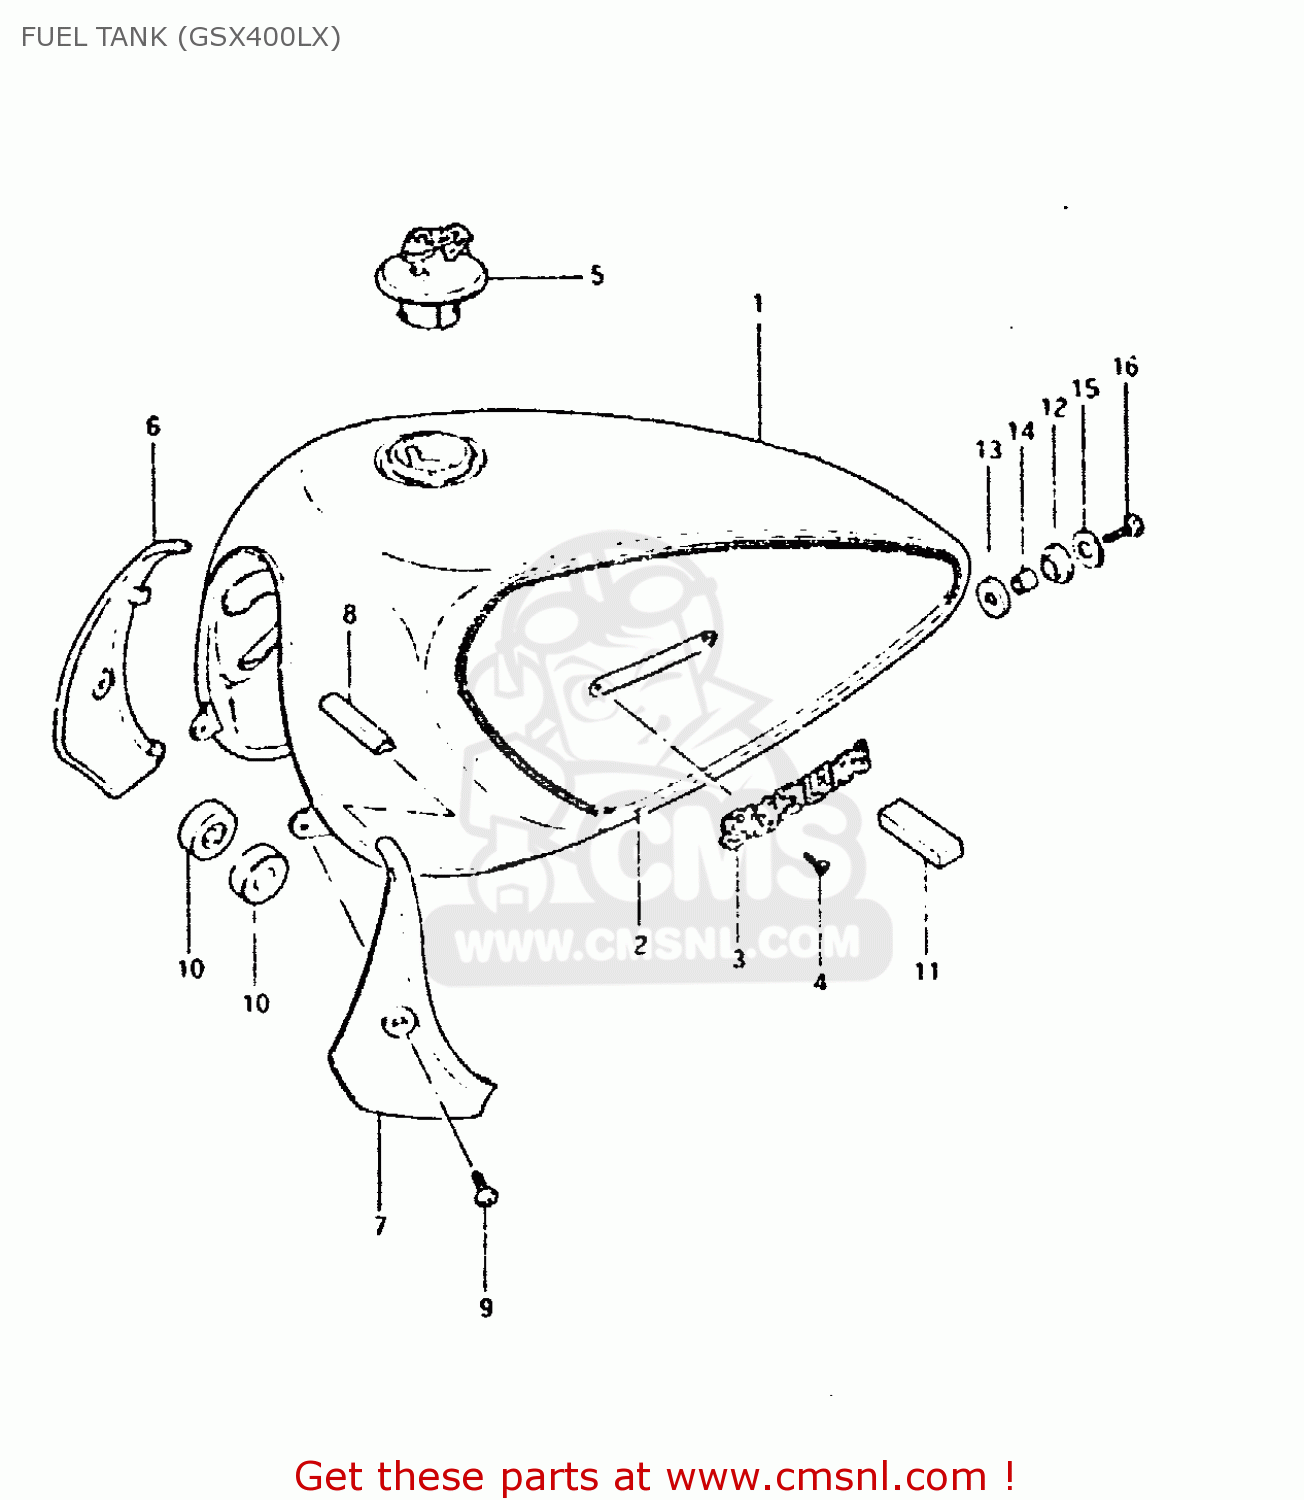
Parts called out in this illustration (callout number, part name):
1	TANK ASSEMBLY,FUEL
2	TAPE SET,FUEL TANK
3	EMBLEM,FUEL TANK
4	SCREW 3X6
5	CAP SET,FUEL TANK
6	COVER,FUEL TANK,FRONT,RIGHT
7	COVER,FUEL TANK,FRONT,LEFT
8	TUBE, FRONT
9	SCREW 6X12
10	CUSHION
11	CUSHION
12	CUSHION
13	CUSHION
14	SPACER(8.5X12X19)
15	WASHER (8.5X29X1.6)
16	BOLT (8X30)
